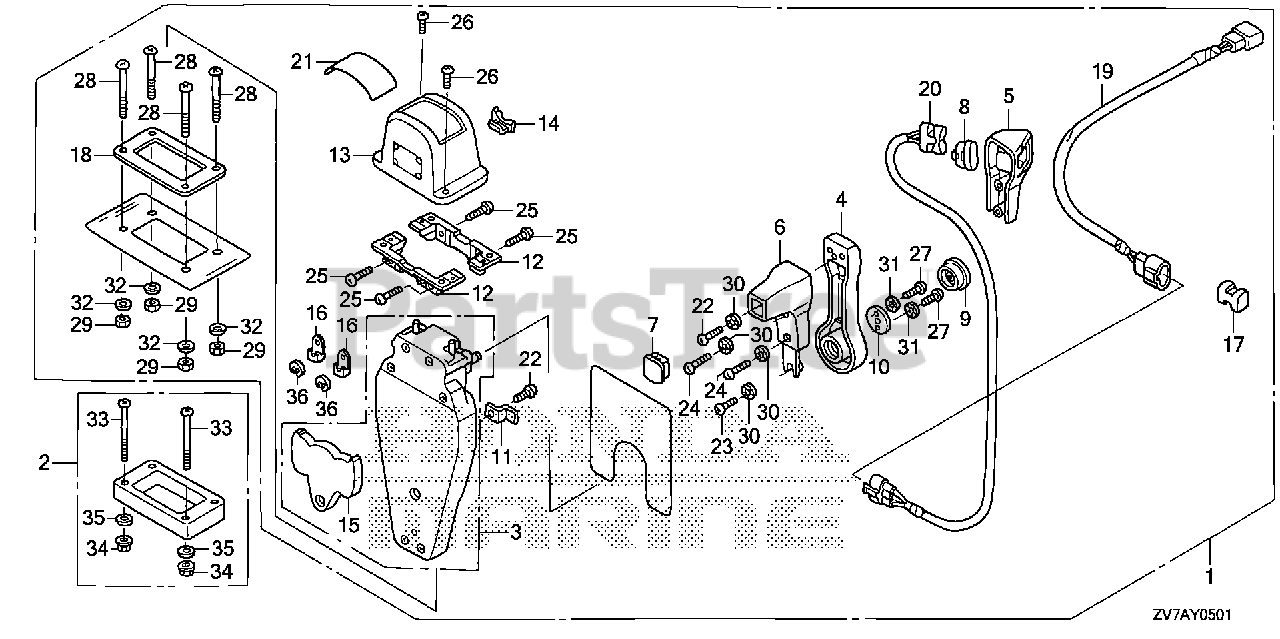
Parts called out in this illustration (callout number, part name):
1	BOX KIT, REMOTE CONTROL (TOP MOUNT SINGLE)(L)
2	SPACER KIT, REMOTE CONTROL BOX (TOP MOUNT SINGLE)
3	HOUSING ASSY., R. (INNER) (TOP MOUNT)
4	HANDLE, REMOTE CONTROL
5	COVER, R. GRIP
6	GRIP, REMOTE CONTROL HANDLE
7	CAP, GRIP
8	CAP, SWITCH
9	BUTTON, THROTTLE
10	PLATE, HANDLE
11	PLATE, CABLE CLAMP
12	BRACKET, REMOTE CONTROL HOUSING
13	HOUSING, REMOTE CONTROL BOX
14	HOUSING, LEAD
15	PLATE, DWELL
16	TERMINAL, CABLE
17	SPACER, CABLE CLAMP
18	GASKET, SINGLE
19	SUB-HARNESS ASSY., POWER TRIM-TILT (B)
20	SWITCH ASSY., POWER TRIM-TILT (B)
21	MARK, REMOTE CONTROL (SINGLE)
22	SCREW, PAN (5X16)
23	SCREW, PAN (5X10)
24	SCREW, PAN (5X20)
25	SCREW, PAN (5X18)
26	SCREW, PAN (4X10)
27	SCREW, PAN (6X18)
28	SCREW, PAN (5X40)
29	NUT, HEX. (5MM)
30	WASHER, LOCK (5MM)
31	WASHER, LOCK (6MM)
32	WASHER, PLAIN (5MM)
33	SCREW, PAN (5X65)
34	NUT, HEX. (5MM)
35	WASHER, PLAIN (5MM)
36	E-RING (6MM)
